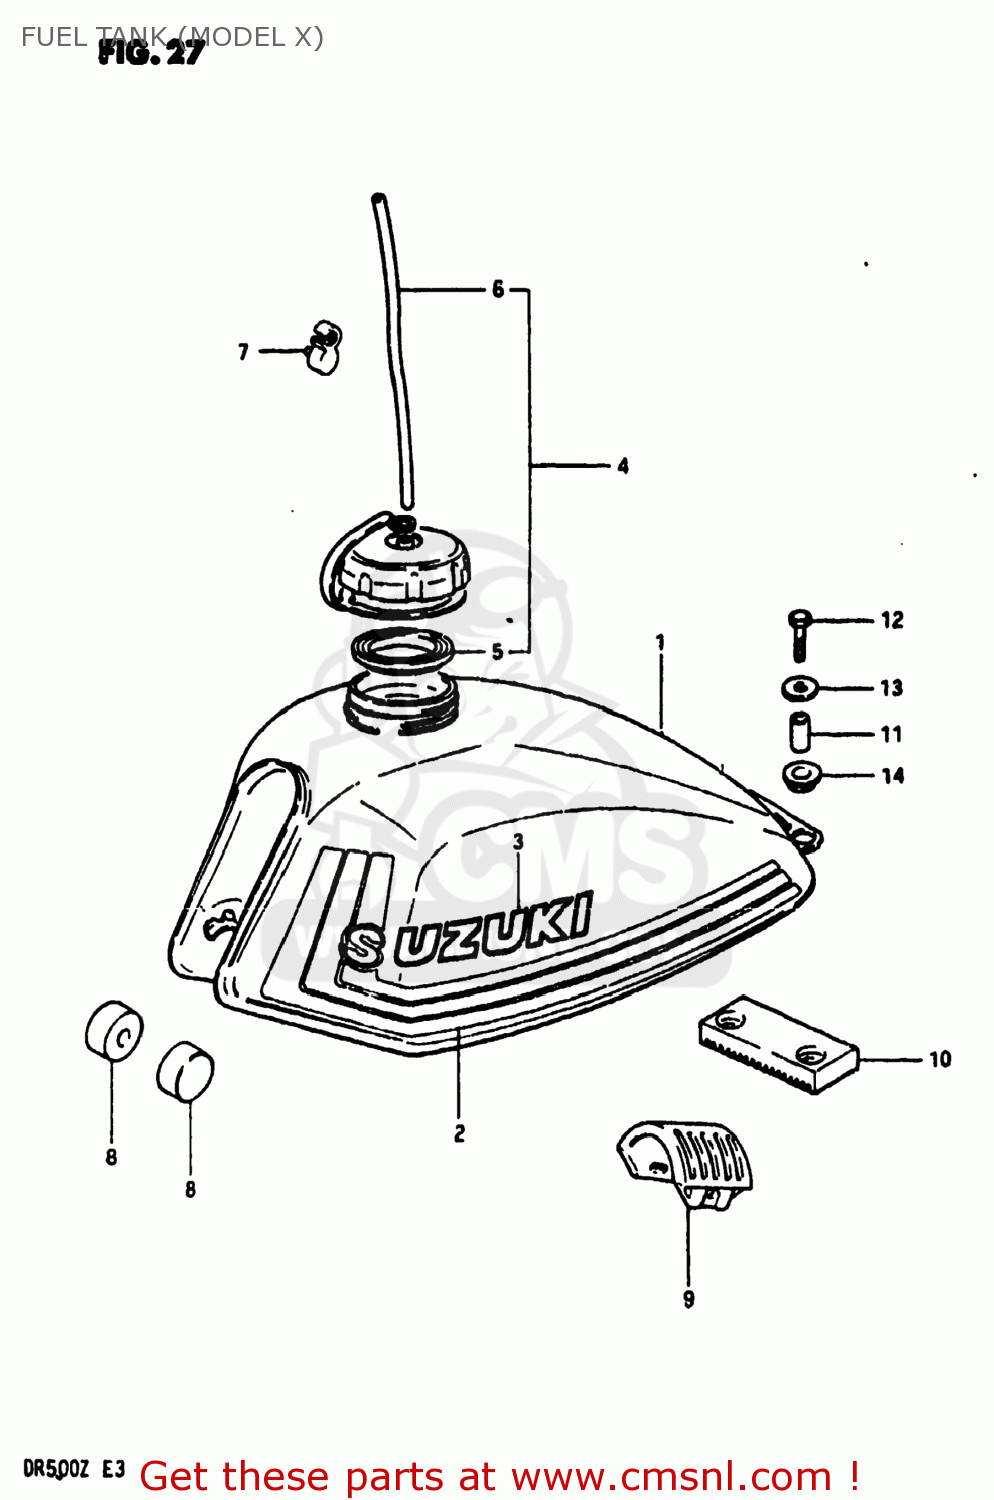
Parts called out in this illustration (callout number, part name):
1	TANK ASSEMBLY,FUEL
2	TAPE SET,FUEL TANK
3	EMBLEM
4	CAP SET,FUEL TANK
5	GASKET,FUEL TANK CAP (NAS)
6	HOSE
7	CLAMP,FUEL TANK BREATHER HOSE
8	CUSHION
9	CUSHION,FUEL TANK UPR FR
10	CUSHION,FUEL TANK,REAR
11	SPACER (6.5X10.5X29)
12	BOLT 6X40
13	WASHER (6.5X24X1.6)
14	CUSHION
